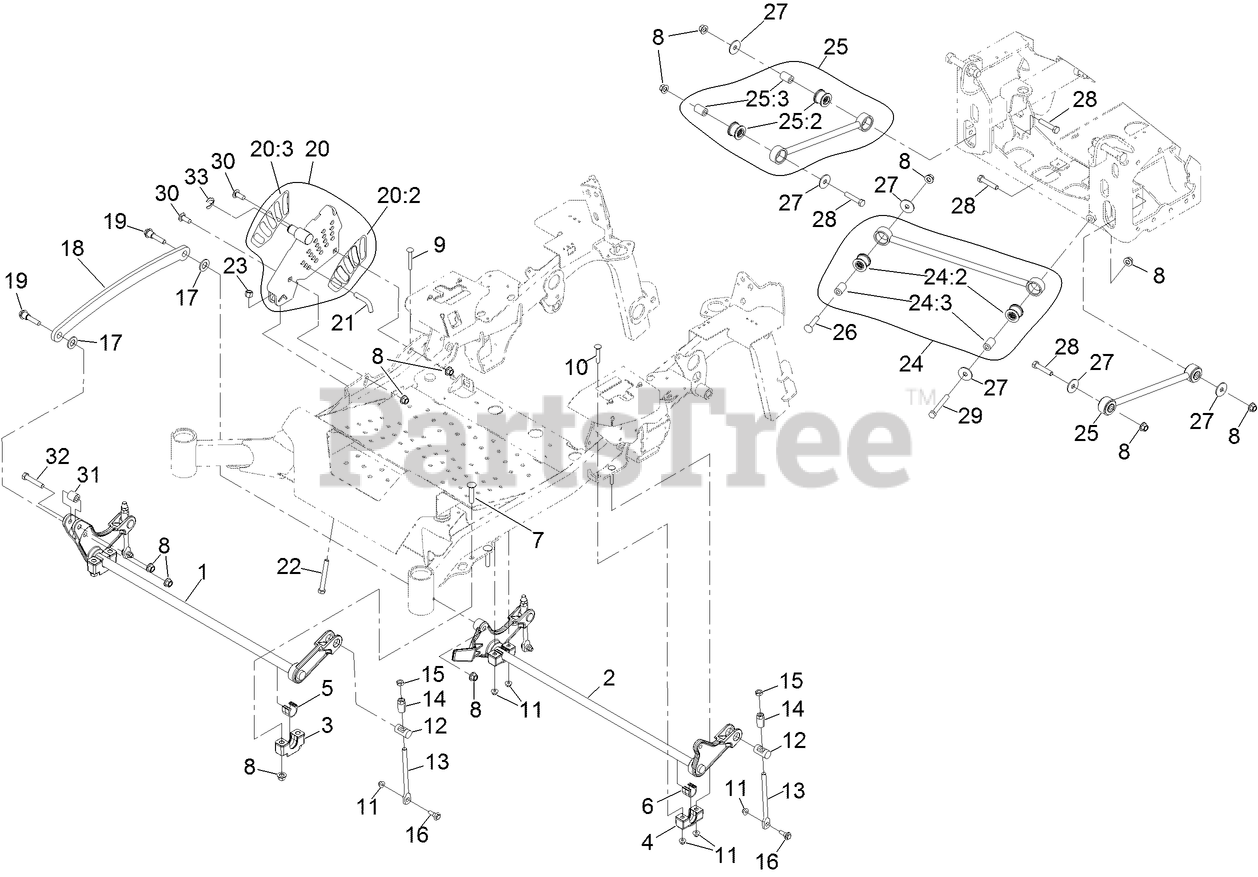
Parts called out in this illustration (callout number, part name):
1	DECKLIFT-FRONT
2	LIFT-DECK, REAR
3	SUPPORT-CROSS SHAFT, BEARING
4	SUPPORT-CROSS SHAFT, BEARING REAR
5	BEARING-CROSS SHAFT, FRON
6	BEARING-CROSS SHAFT, REAR
7	Bolt-Carriage 1/2-13 X 2 1/2 Spl Neck
8	Nut-Lock 1/2-13
9	SCREW-CARR
10	Bolt-Carriage 3/8-16 X 2 1/4
11	NUT-HF, NI
12	TRUNNION
13	LINK-ADJUSTER, DECK LIFT
14	ADJUSTER-LIFT, DECK
15	NUT-JAM
16	SCREW-SHOULDER, HHF
17	WASHER-FLAT
18	LINK-LIFT, DECK
19	SCREW-HHF, SHOULDER
20	HOC ASM
20:2	DECAL-HEIGHT OF CUT
20:3	DECAL-HEIGHT OF CUT, OUTER
21	PIN-HOC
22	BOLT-TAP
23	NUT-LOCK, NI
24	PANHARD ROD ASM
24:2	BUSHING-SUSPENSION, RUBBER
25	DECK STRUT ASM
25:2	BUSHING-SUSPENSION, RUBBER
26	SCREW-CARR
27	WASHER-THRUST
28	SCREW-HH
29	SCREW-HH
30	SCREW-CARR, SHORT NECK
31	SPACER-PIVOT
32	SCREW-HH
33	RING-RETAINING
